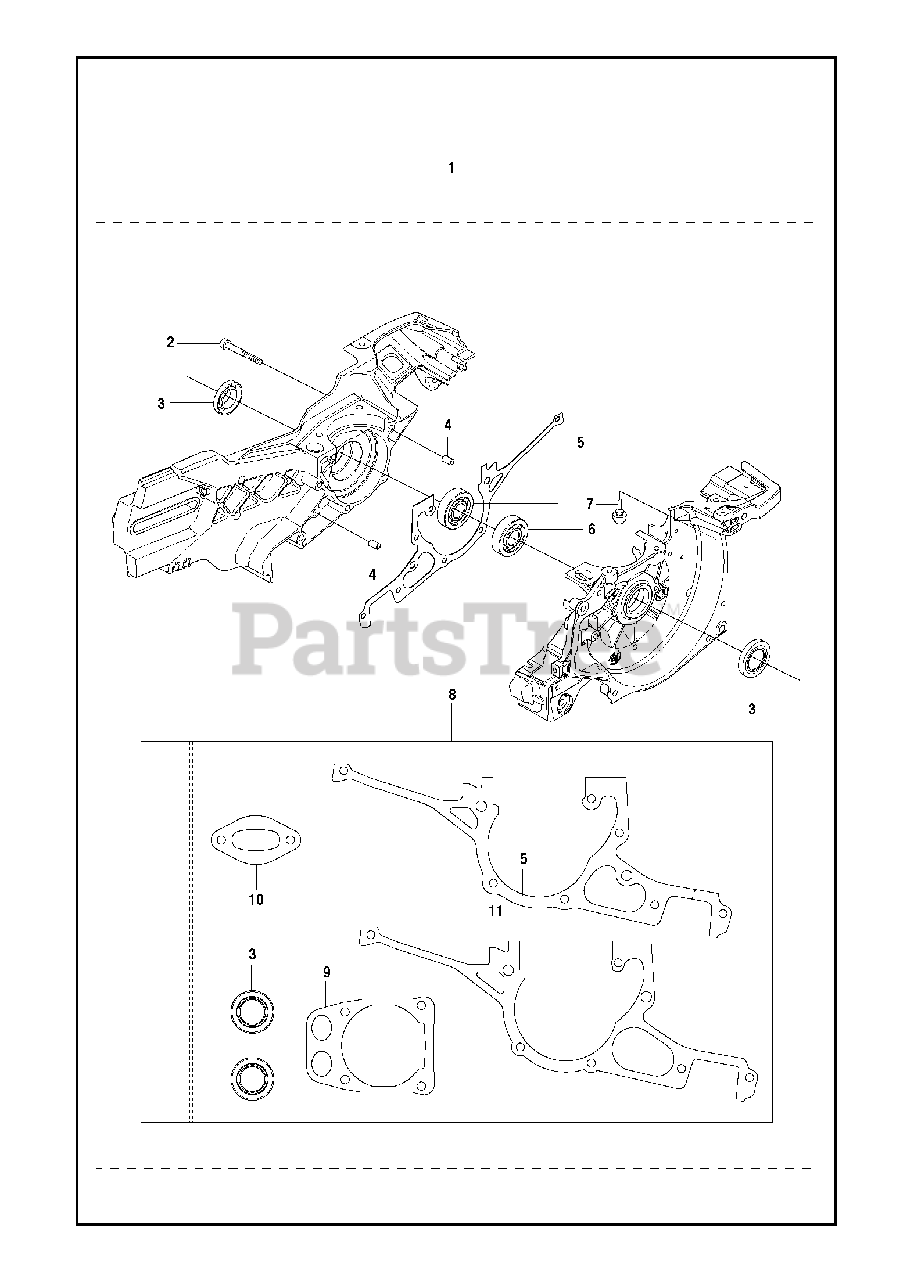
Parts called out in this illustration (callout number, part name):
2	SCREW ITXSCM
3	SEALING RING
4	GUIDE BUSHING
6	BALL BEARING
7	RUBBER BUSHING
8	GASKET KIT
10	GASKET
